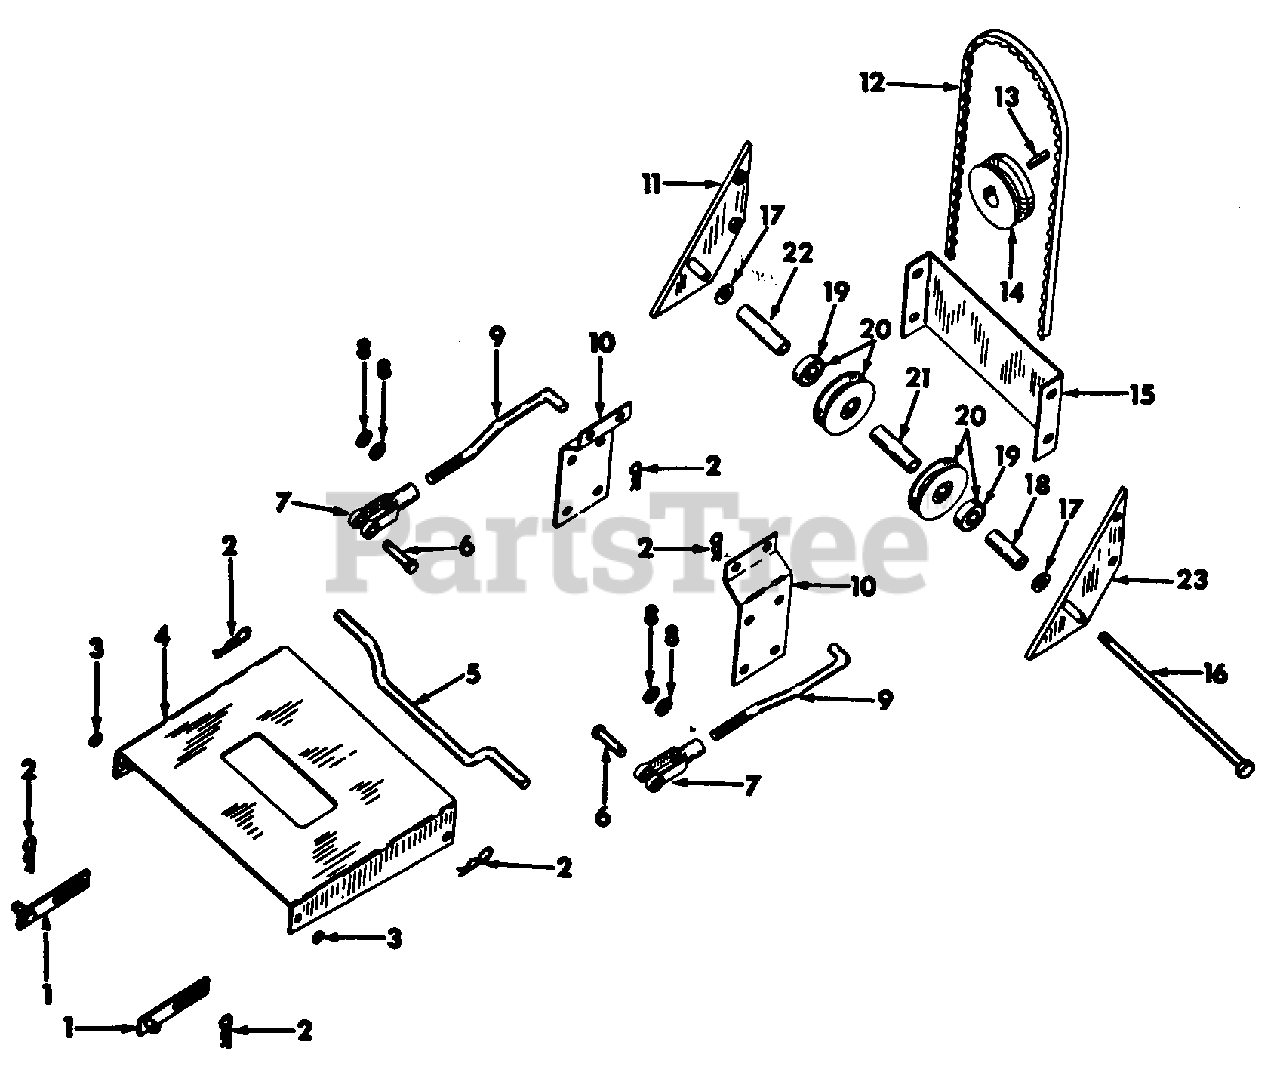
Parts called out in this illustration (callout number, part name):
1	Link Assy, Lift
2	Pin, Quick Attachable Cotter
4	Link Assy, Lower Parallel
5	Rod, Lower Link Pivot
6	Pin, Rod End Clevis
7	Clevis, Rod End 1/2-20
8	Washer, 17/32 X 7/8 X 8 Ga
9	Rod, Upper Link
10	Strip, Upper Parallel Link
11	Support Assy, Tightener LH
12	Belt, Drive
13	Key, 1/4 Sq X 1 Parallel
14	Pulley, Engine
15	Shield, Front Pulley
16	Bolt, 5/8-11 X 10 C-Z Hex-Hd Mach
17	Washer, 21/32 X 1-1/4 Ga
18	Spacer, Right Idler
19	Bearing, Pulley Ball
20	Pulley Assy, Tightener
21	Spacer, Center Idler
22	Spacer, Left Idler
23	Support Assy, Tightener RH
